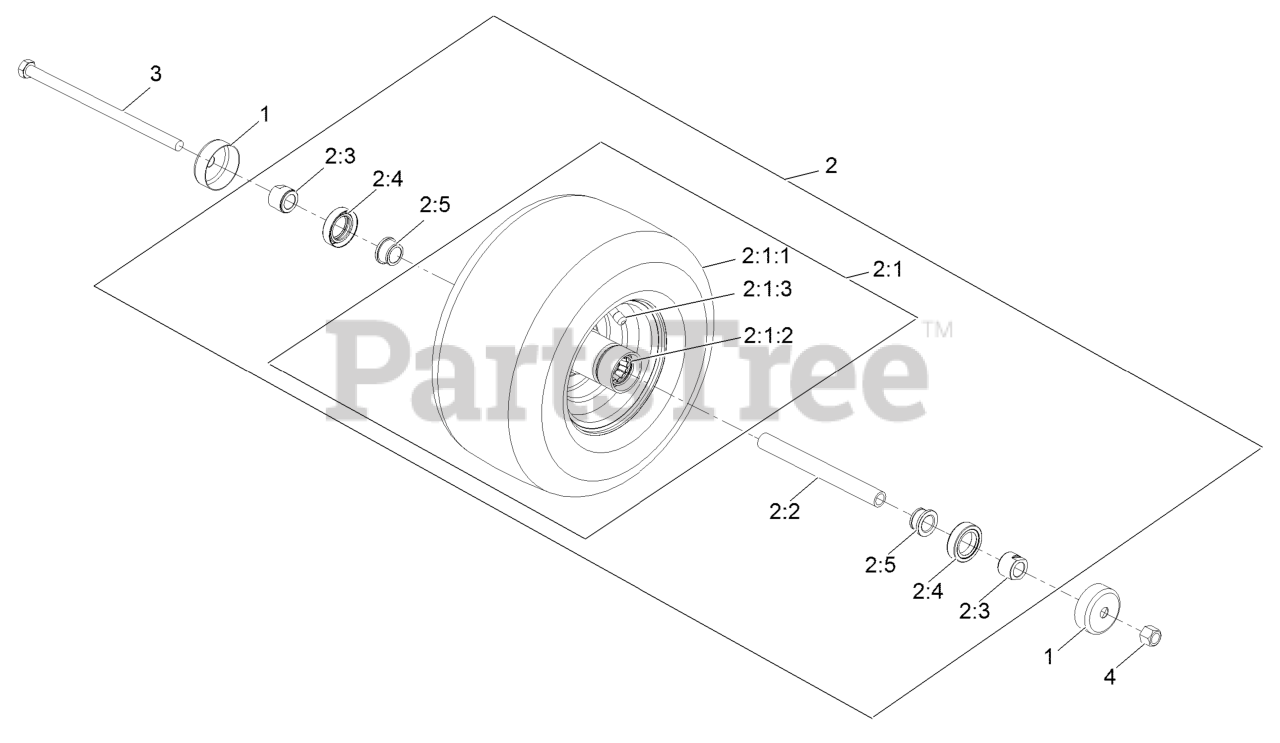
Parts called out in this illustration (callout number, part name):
1	GUARD-SEAL
2	Wheel ASM
2:1	Wheel And Tire ASM
2:1:2	BEARING-CUP
2:1:3	VALVE
2:2	AXLE CASTER ASM
2:3	SPACER-NUT
2:4	SEAL-CASTER
2:5	BEARING-CONE, TAPERED ROLLER
3	SCREW-HH
4	NUT-LOCK, NI
